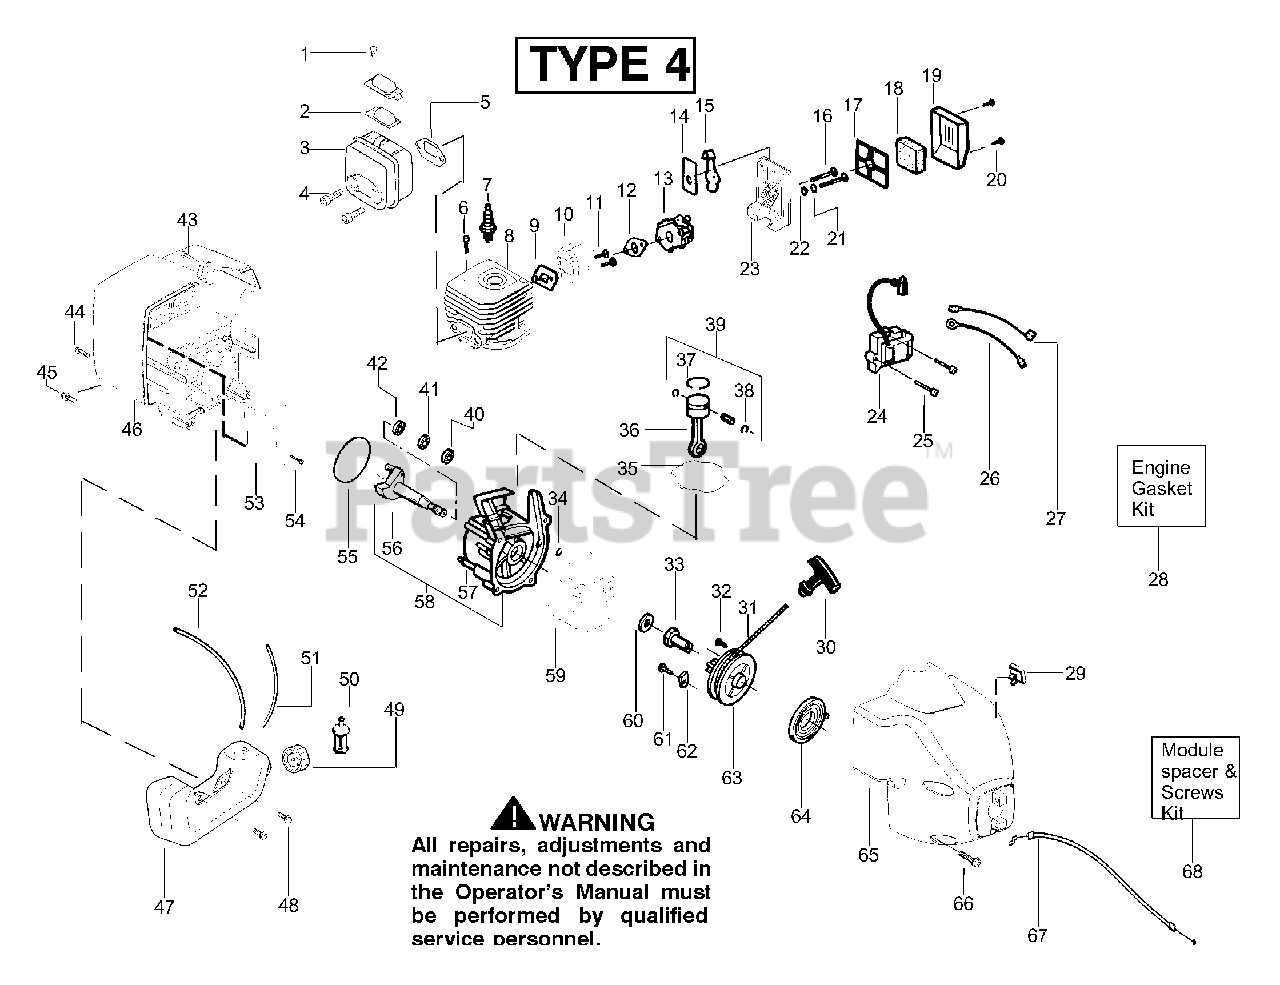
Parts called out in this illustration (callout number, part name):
1	Screw-screen
2	Kit-Spark Arrestor
3	Kit-Muffler
4	Bolt-Muffler
5	Gasket-Muffler (kit)
6	Screw-Cylinder
7	Spark Plug (RCJ-6Y)
8	Kit-Cylinder
9	Gasket-Cyl/Carb.(kit)
10	Carb. Adapter
11	Screw-Carb Adptr.
12	Gasket-Carb.(kit)
13	Kit-Carb. Ass'y.
14	Choke Plate
15	Choke Shutter
16	Screw-Carburetor
17	Filter Support Plate
18	Air FIlter Foam
19	Air Filter Cover
20	Screw-Air Box
21	Choke Spacer
24	Ignition Module
25	Screw-Ignit. Module
26	Assy-Ground Wire
27	Assy-Lead Wire
28	Kit-Engine Gasket
29	Kit-Switch-Off/On
30	Handle-Starter
31	Kit-Rope
33	Coupling-Drive
34	Ret. Ring/C'shaft
35	Seal-Cylinder(kit)
36	Assy-Connecting Rod
37	Ring-Piston
38	Retainer-Piston Pin
39	Kit-Piston
40	Bearing-Outer
41	Seal-C'case
42	Bearing-Inner
43	Screw-Shd/Fan Hsg
44	Screw
46	Rear Shroud
47	Assy-Fuel Tank
48	Retainer-Tank
49	Assy-Fuel Cap
50	Assy-Fuel Pickup
51	Fuel Line (Small)
52	Fuel Line (Large)
53	Shield-Heat
54	Screw-Heat Shield
55	O-ring-C'case(kit)
56	Assy-Crankshaft
57	Assy-Crankcase
58	Assy-c'case/c'shaft
59	Assy-Flywheel
60	Washer-Flat
61	Screw-Pulley
62	Retainer-Pulley
63	Kit-Starter Pulley
64	Spring-Starter
65	Assy.-Fan Hsg.
66	Screw
67	Assy-Throttle Cable
68	Kit-Module Spacer & Screws
